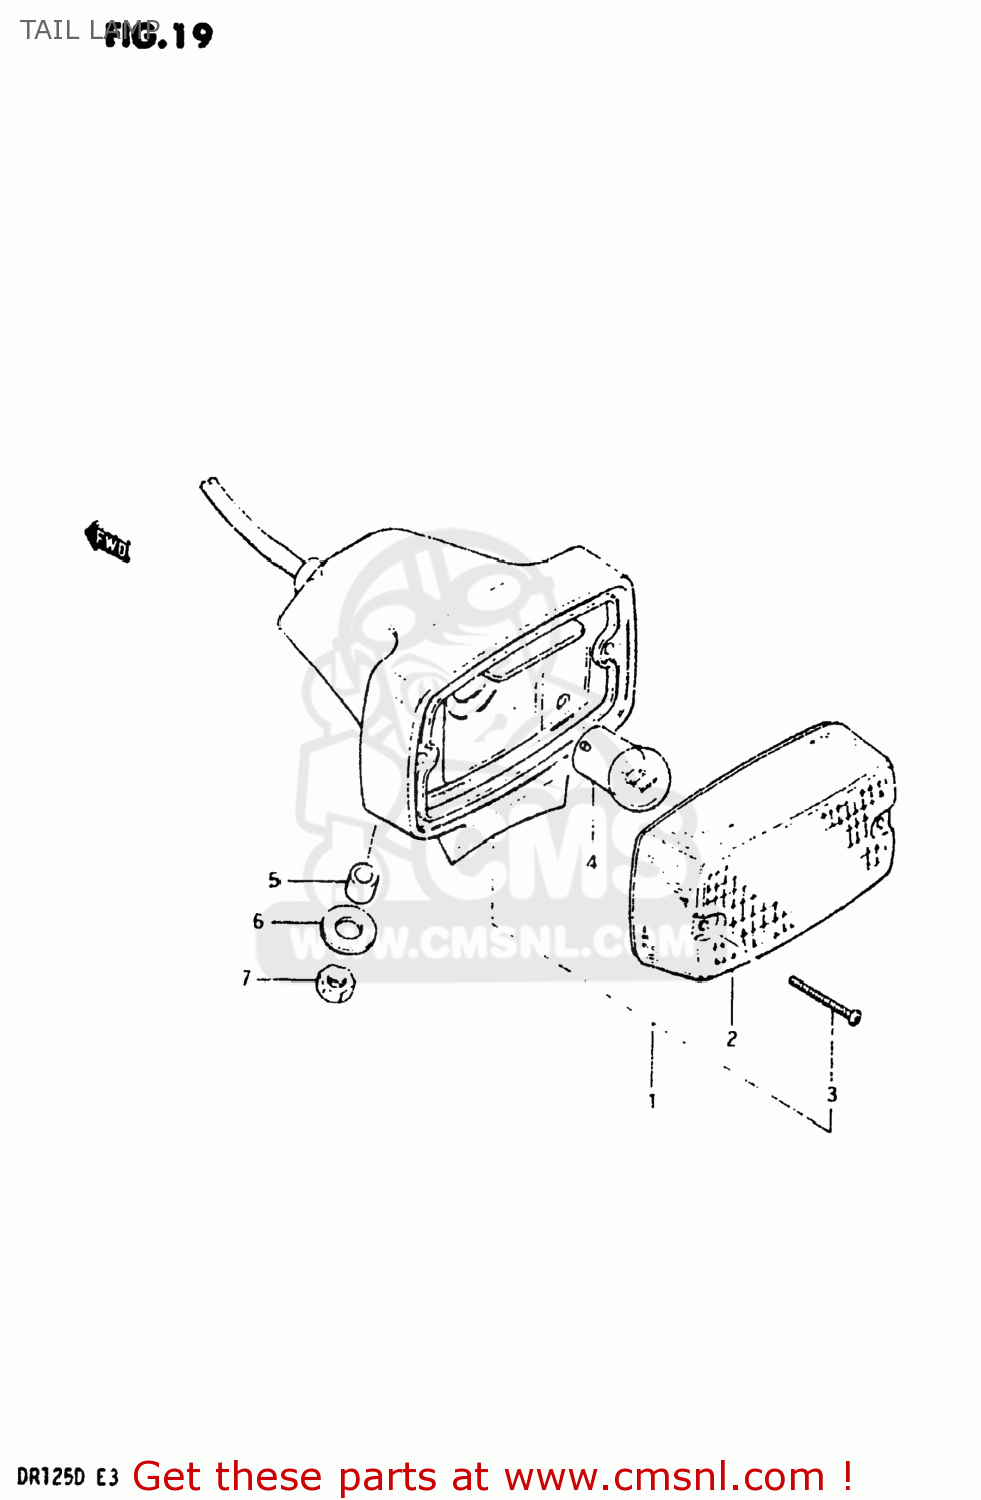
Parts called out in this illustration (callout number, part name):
1	LAMP ASSEMBLY,TAIL
2	LENS
3	SCREW,REAR COMBINATION LAMP LENS
4	BULB(6V5W,TOKAI DENSO)
5	SPACER (6.3X9.1X6.7)
6	WASHER
7	NUT
